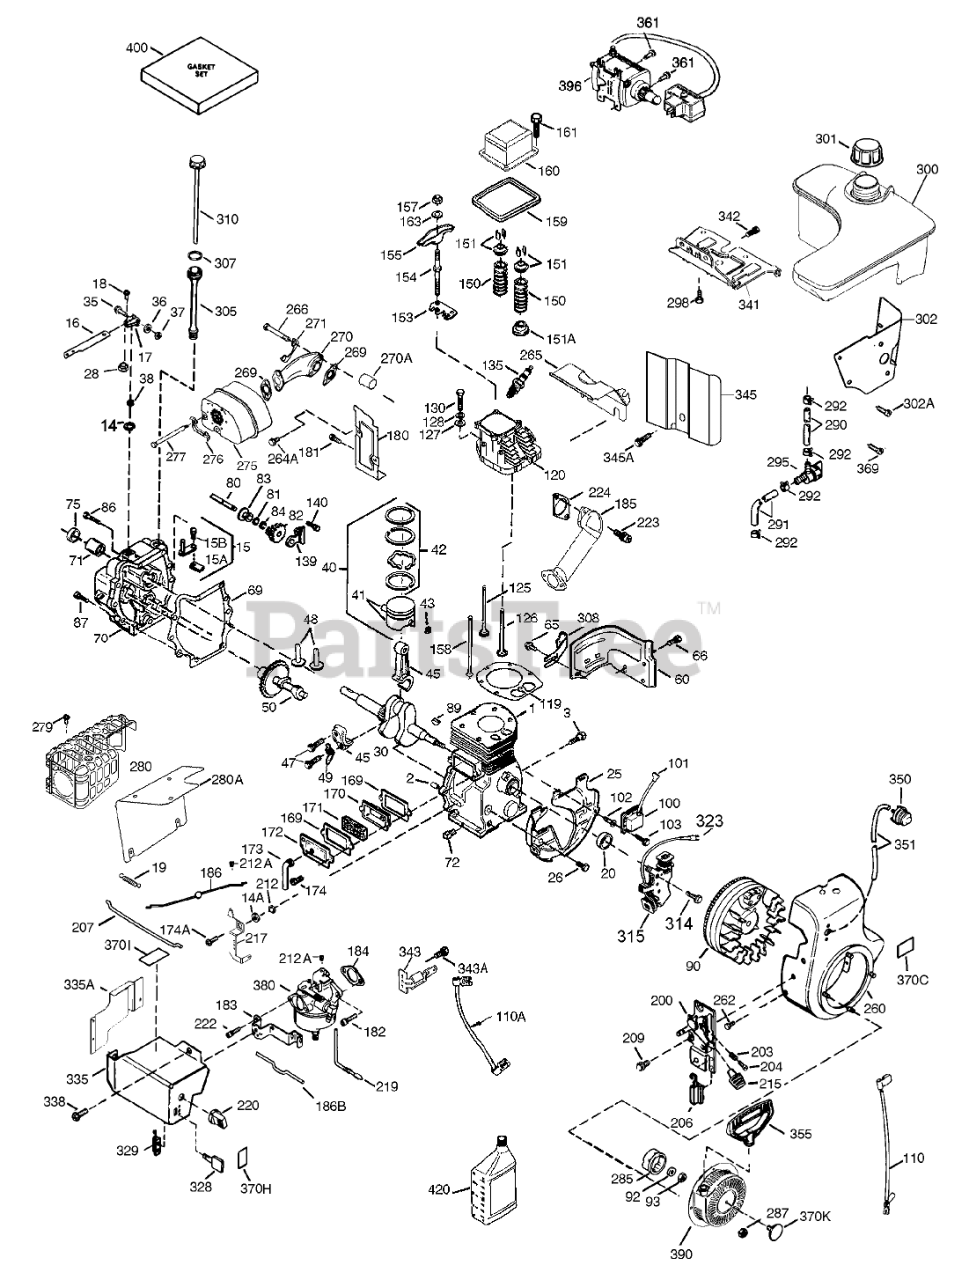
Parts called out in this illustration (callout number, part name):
1	Cylinder (Incl. Ref. #2, 20 & 72)
2	Pin-Dowel
3	Screw (1/4-20x1/2)
14	Washer-Flat
14A	Washer
15	Governor Rod (Incl. Ref. #15A & 15B)
15A	Yoke-Governor
15B	Screw (6-40x5/16)
16	Lever-Governor
17	Clamp-Lever, Governor
18	Screw (T-15, 8-32x7/16)
19	Spring-Extension
20	Seal-Oil
25	Baffle-Housing, Blower
26	Screw (1/4-20x19/32)
28	Nut-Lock
30	Crankshaft
35	Screw
36	Washer-Lock
37	Nut-Lock
38	Ring-Retaining
40	Piston-Pin and Ring Set (STD)
40	Piston- Pin and Ring Set (.010 O S)
41	Piston & Pin Ass-y (Std.)(Incl. Ref.#43)
41	Piston & Pin Ass-y (.010)(Incl. Ref.#43)
42	Ring Set (STD)
42	Ring Set (.010 O S)
43	Ring-Retaining, Piston Pin
45	Connecting Rod ASM (Incl. Ref.# 47 & 49)
47	Bolt-Rod, Connecting
48	Lifter-Valve
49	Oil Dipper
50	Camshaft (MCR)
60	Extension-Housing, Blower
65	Screw (10-24 x 9/16)
66	Screw
69	Gasket-Cover, Cylinder
70	Cylinder Cover (Incl. Ref. #71, 75 & 80-84)
71	Bushing-Crankshaft
72	Plug-Drain, Oil (SQH 1/4-18)
75	Seal-Oil
80	Shaft-Governor
81	Washer
82	Governor Gear ASM (Incl. Ref. #81)
83	Spool-Governor
84	Ring-Retaining
86	Screw (1/4-20x1-3/16)
87	Screw (1/4-20x1-11/16)
89	Key-Flywheel
90	Flywheel ASM
92	Washer-Belleville
93	Nut-Flywheel
100	Solid State Ignition (Incl. Ref. #101)
101	Cover-Spark Plug
102	Stud-Mounting, Solid State
103	Screw (T-15, 10-24 x 15/16)
110	Wire-Ground
110A	Wire-Ground
119	Gasket-Head, Cylinder
120	Cylinder Head(Incl. Ref. #151A & 270A)
125	Valve-Exhaust (STD)
125	Valve-Exhaust (1/32)
126	Valve-Intake (STD)
127	Washer-Flat
128	Washer-Belleville
130	Screw (5/16-18 X 2-1/2)
135	Spark Plug-Resistor (R N 4C)
139	Bracket-Gear, Governor
140	Screw (10-24x1/2)
150	Spring-Valve
151	Keeper-Spring, Valve
151A	Cap-Spring, Valve
153	Guide-Rod, Push
154	Stud-Arm, Rocker
155	Arm-Rocker
157	Nut-Jam
158	Rod-Push
159	Gasket-Cover, Rocker Arm
160	Cover-Arm, Rocker
161	Screw
163	Washer
169	Gasket-Cover, Valve
170	Body-Breather
171	Element-Breather
172	Cover-Valve
173	Tube-Breather
174	Screw
174A	Screw (10-24 X 29/32)
180	Extension-Housing, Blower
181	Screw (10-24 x 9/16)
182	Screw (T-30, 1/4-20 X 27-32)
183	Bracket-Choke
184	Gasket-Carburetor To Intake Pipe
185	Pipe-Intake
186	Link-Governor
186B	Spring-Choke
200	Control Bracket (Incl. Ref. #203, 204 & 206)
203	Spring-Compression
204	Screw (T-10, 5-40x7/16)
206	Terminal
207	Link-Throttle
209	Screw (10-32 x 1/2)
212	Bushing
212A	Bushing
215	Knob-Control
217	Lever-Bellcrank
219	Rod-Choke
220	Knob-Control
222	Screw (10-32 x 1/2)
223	Screw (T-30, 5/16-18 X 7/8)
224	Gasket-Pipe
260	Housing-Blower
262	Screw
264A	Screw (1/4-20 X 5/8)
265	Cover-Head, Cylinder
266	Screw (5/16-18 X 1-9/32)
269	Gasket-Manifold, Exhaust
270	Manifold, Exhaust
270A	Liner-Port, Exhaust
271	Plate-Locking
275	Muffler
276	Plate-Locking
277	Screw (5/16-18 X 4-1/2)
279	Screw
280	Shield-Heat
285	Cup-Starter
287	Nut and Lock Washer (1/4-28)
290	Line-Fuel
291	Line-Fuel (8.62)
292	Clamp-Line, Fuel
295	Fuel Shut-Off Valve (Incl. Ref. #292)
298	Screw (1/4-15x7/8)
300	Fuel Tank (Incl. Ref. #292 & 301)
301	Cap-Fuel
302	Extension-Tank, Fuel
302A	Screw (10-32 x 1/2)
305	Tube-Fill, Oil
307	O-Ring
308	Clip-Tube, Fill
310	Dipstick
314	Screw (1/4-20 x 3/4)
315	Alternator Coil (18 Watt)(Incl. Ref. #322 & 323)
322	Body-Connector
323	Terminal
328	Key-Ignition
329	Terminal
335	Spring
335A	Cover-Carburetor
338	Screw (10-32 x 1/2)
341	Bracket-Tank, Fuel
342	Screw (5/16-18 X 7/8)
343	Key Switch Bracket (Incl. Ref. #343A)
343A	Screw (8-32 x 23/64)
345	Baffle-Heat
345A	Screw (10-32 x 1/2)
350	Primer ASM
351	Line-Primer
355	Handle-Starter, Mitten Grip
361	Screw (T-30, 1/4-20x15/32)
369	Screw (12-16 x 5/8)
370C	Decal-Primer, International Symbol
370H	Decal-Choke
370I	Decal-Warning (Bilingual)
370K	Decal-Tecumseh Logo for Top of Recoil Starter
380	Carburetor (Incl. Ref. #184)
390	Starter-Rewind
396	Starter-Electric (110 Volt)
400	Gasket Set
420	Oil-Engine, S A E 5W30
